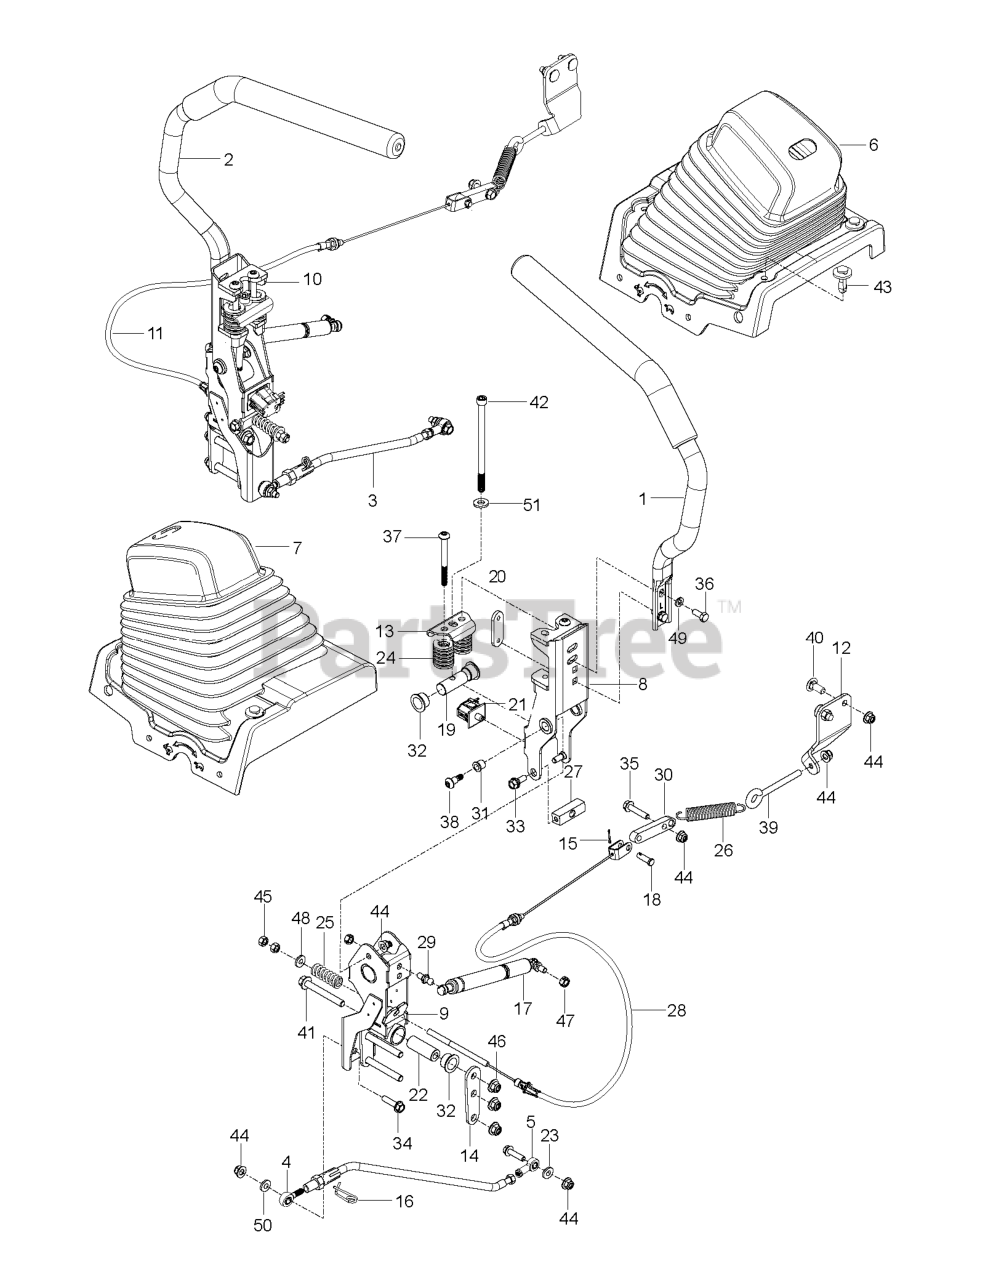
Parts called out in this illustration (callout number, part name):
1	LEVER.ASM.DRIVE.LH
2	LEVER.ASM.DRIVE.RH
3	KIT.CONTROL.LINKAGE.RIGHT
3	ROD.ASM.CONTROL.PZ.5400.LH
4	ROD.END.MALE.LH.THREAD
5	JOINT.HEIM.FEML.5/16.RH.THREAD
6	BELLOWS.LH.DRIVE.LEVER
6	KIT.SERVICE.LEVER.BELLOW.LH
7	BELLOWS.RH.DRIVE.LEVER
7	KIT.SERVICE.LEVER.BELLOW.RH
8	KIT.CARRIER.UPPR.W/BUSHINGS.LT
9	KIT.CARRIER.LWR.W/BUSHINGS
10	KIT.CONTROL.MECHANISM.LEFT
11	KIT.CABLE.BRAKE.PARKING.LEFT
12	BRACKET.PNT.RETRN.SPRNG.LH.BLK
13	BRACKET.RETAINING.SPRING
14	BRACKET.PNT.CONTROLS.MTG.EDIP
15	RETAINER CLIP
16	CLIP.RETAINER.CONTROLS
18	PIN.CLEVIS.5/16.DIA.3/4.USABLE
21	SWITCH.SNPMNT.DELTA.NCNC.PZREF
22	SPACER.PIVOT
23	SPACER.7_16OD;5_16ID;STEP.UP
24	SPRING 1.25"ODX1.5"L
25	SPRING, BRAKE ROD
26	SPRING.RETURN.BRAKE
27	CABLE.YOKE.PARK.BRAKE
28	CABLE.BRAKE.PARK
29	STUD.BALL.10MM
30	BRACKET.EXTENSION
31	BEARING.FLG.3/8.SHAFT.1/2.HSG
32	BEARING, FLANGE
33	BOLT, SHOULDER
34	HHFS 5/16-18 X 1.25 TPBLT GD 5
35	HHFS 5/16-18 X 1.5 GD 5
36	HCS 5/16C X 3/4
37	SCREW.SHCS.5/16-18 X 3-1/2"
38	SCREW.SHLDR.3/8 X 1/2.5/16-18
39	EYE BOLT 5/16 X 3.50
40	RHSNB 5/16C X 1
41	HHFS 3/8-16 X 3 GRD 5 ZD
42	SCREW.SHCS.3/8-16 X 6L.ZY
43	RIVET.PUSH.PIN.0.25IN.HOLE
44	5/16-18 NYLOC FLANGE NUT
46	NUT 3/8-16 HEX FLG NYLOC ZD
47	NUT 5/16C CENTERLOCK
48	WASHER.5/16.FLAT.STE.STD.
49	WASHER.LOCK.HVY.HLCL.SPR.5/16
50	WASHER
51	WASHER, 3/8 THICK
